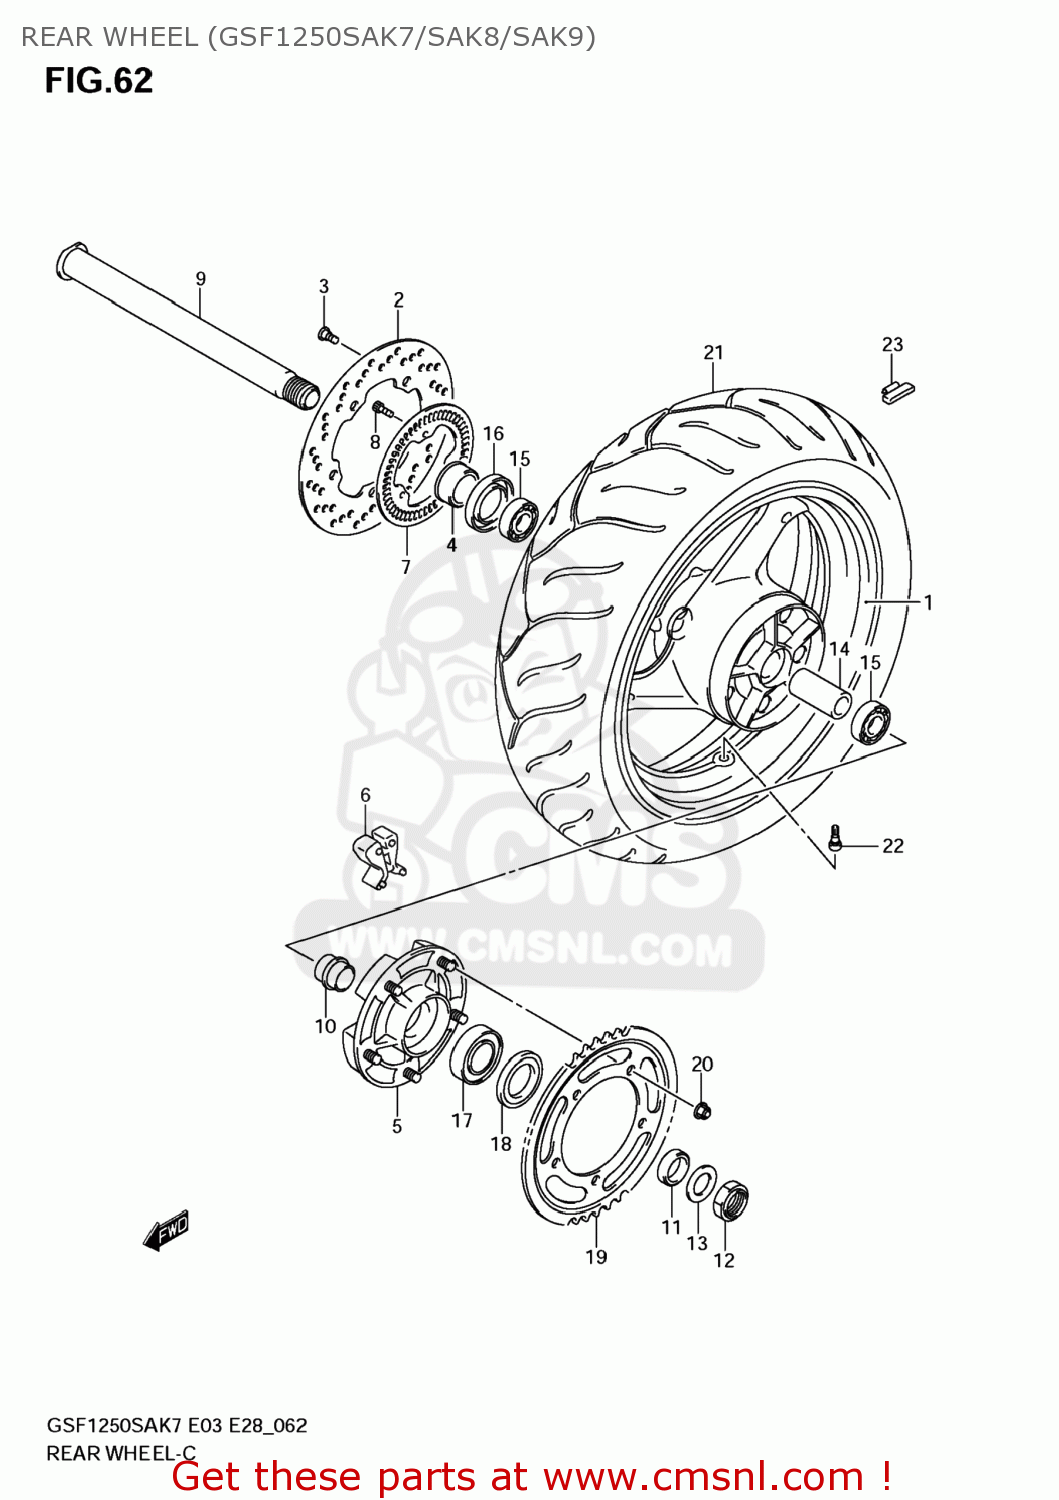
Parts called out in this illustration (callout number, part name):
1	WHEEL,RR(17M/CXMT5.50)
2	DISC,RR BRAKE
3	BOLT(8X21)
4	SPACER,RR AXLE,R
5	DRUM,RR SPROCKET
6	ABSORBER,RR HUB SHOCK
7	RING,SPEED SENSOR FR(50T)
8	BOLT
9	AXLE,RR
10	RETAINER,RR SPROCKET DRUM
11	SPACER,RR AXLE,L
12	NUT
13	WASHER(25.2X42X3.2)
14	SPACER,RR HUB BEARING
15	BEARING(28X52X12)
16	SEAL,OIL(37X52X8)
17	BEARING
18	SEAL,OIL(39X65X7)
19	SPROCKET,REAR(
20	NUT
21	TIRE,RR(180/55 ZR17M/C 73W)
22	VALVE ASSY,WHEEL RIM(TR412)
23	BALANCER,WHEEL(10G)
